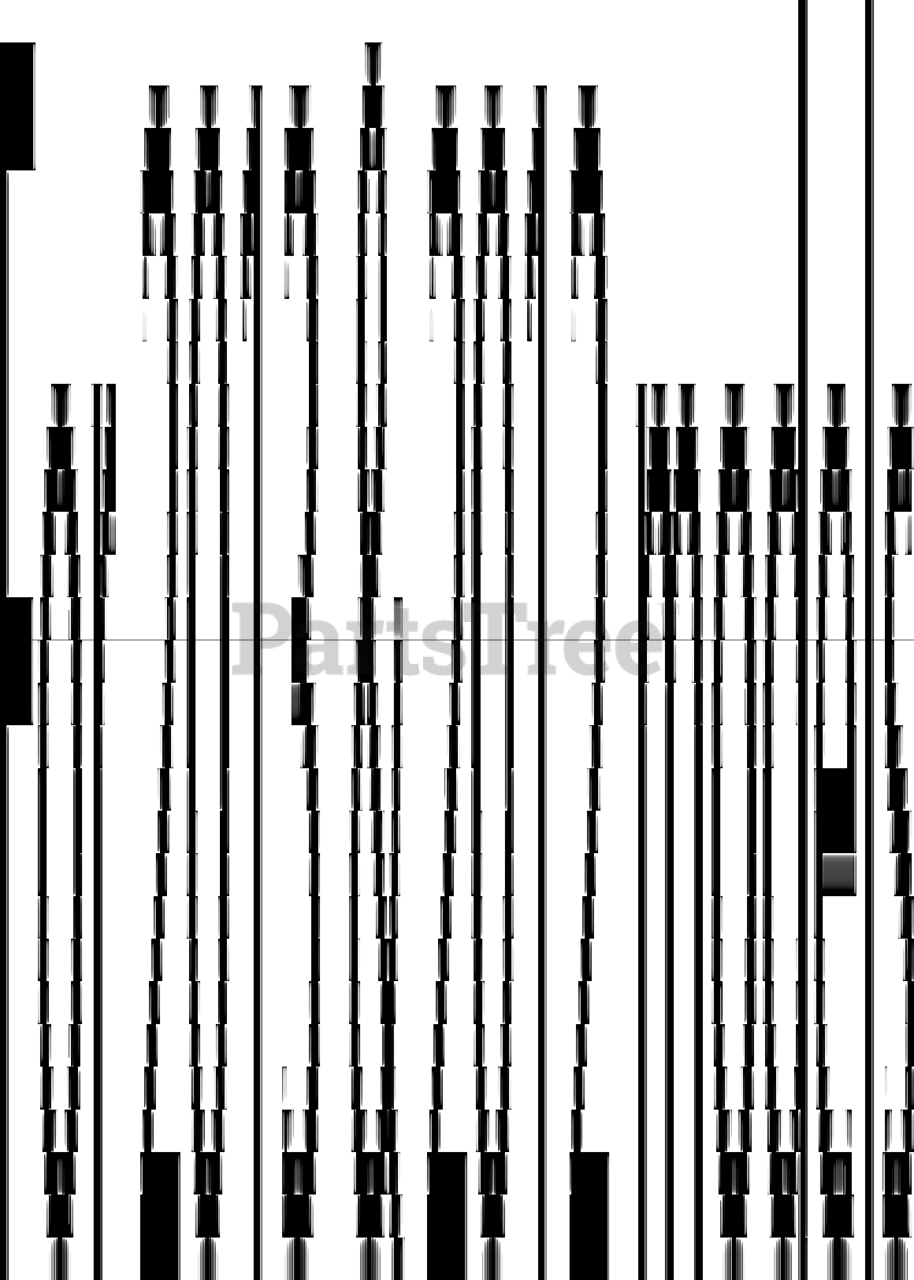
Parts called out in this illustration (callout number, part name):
1	BLADE
1	BLADE - BULK PACK 500 PCS
1	BLADE - 30 PCS
1	BLADE KIT
2	BLADE BLADE KIT INCL PACKAGING
2	BLADE 9PCS EXTRA THICK
2	BLADE 300PCS -SINGLE HOLE THIC
2	BLADE CARBON STEEL, THICK BLAD
3	USB SERVICE CABLE
5	GREASE 300 ML
6	GREASE OKS 110 85ML
6	SEALANT
7	N/A PIN CODE TRANSFER UNIT ADA
8	TEST EQUIPMENT
9	WALL BRACKET ASSY
10	SIGNAL BOOSTER
11	BRUSH KIT BRUSH X6, HOLDER X2,
11	BRUSH KIT
12	BRUSH KIT
12	BRUSH KIT - ONLY BRUSHES 6 PCS
14	WHEEL ASSY
14	HEAVY FRONT WHEEL KIT INCL PAC
15	GPS UNIT
16	AUTOMOWER SHELTER
17	SCREW KIT CS
18	TOP INCL LOGO & WINDOW CHARG
19	LOCK WASHER
20	AXLE CHARGING STATION COVER
22	FRONT CHARGING STATION COVER
